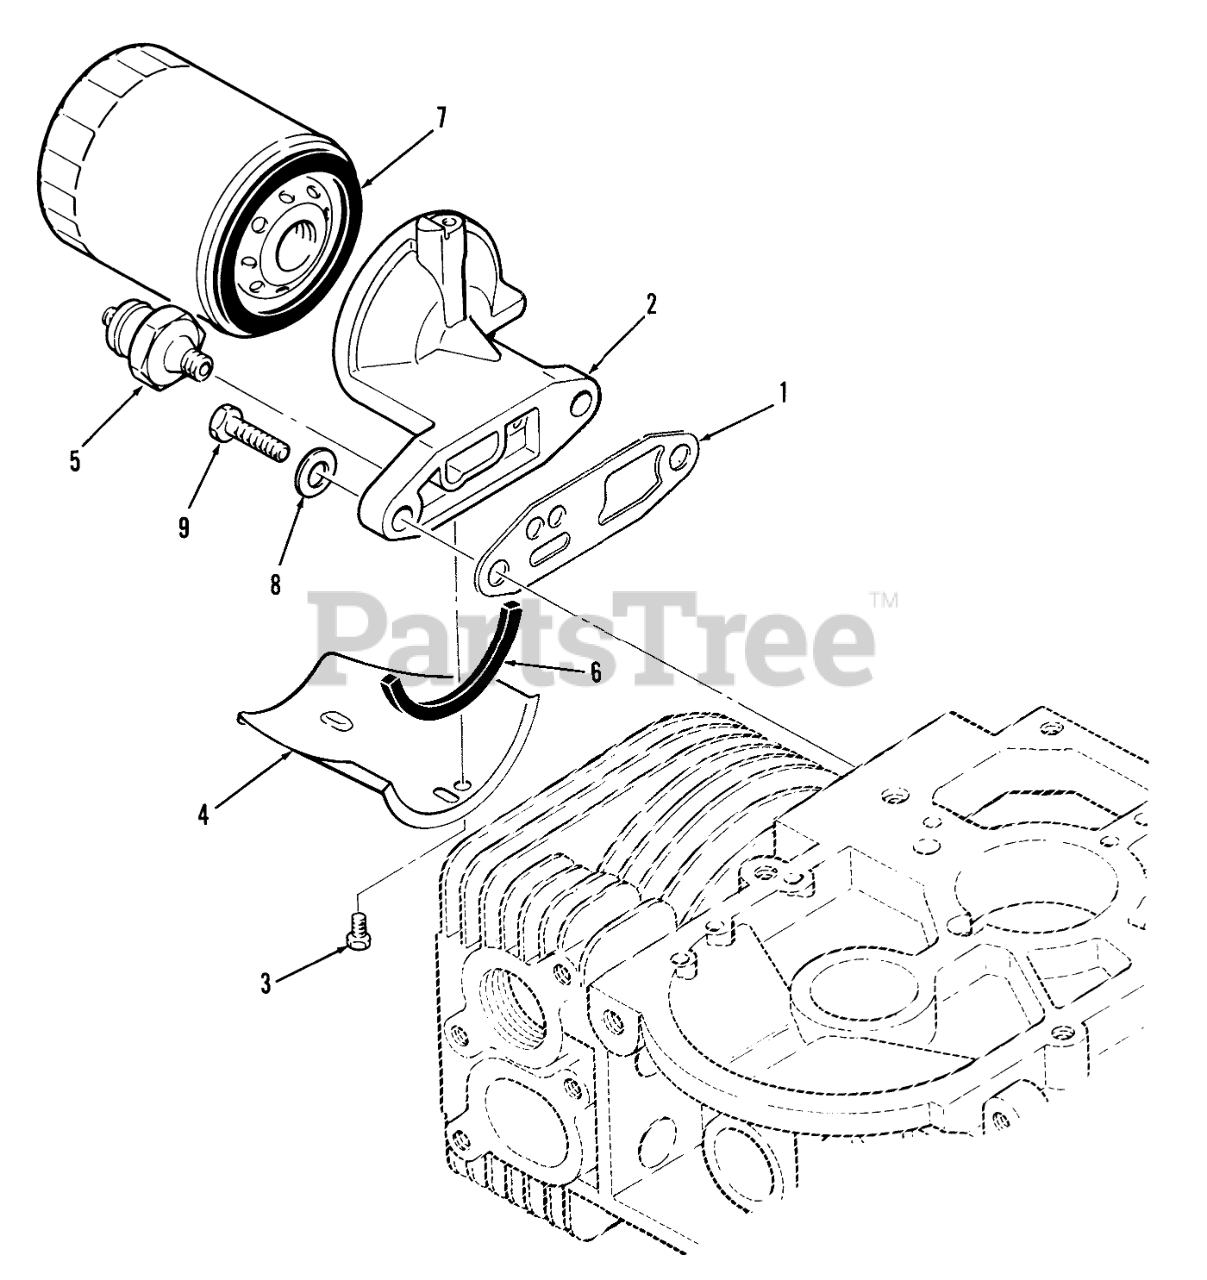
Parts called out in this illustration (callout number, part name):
1	Gasket
2	Adapter
3	Bolt
4	OIL-DRAIN
5	OIL-PRESSURE SWITCH
6	OIL-DRAIN SEAL
7	Oil Filter
8	Washer
9	HHCS 5/16-18 X 1
